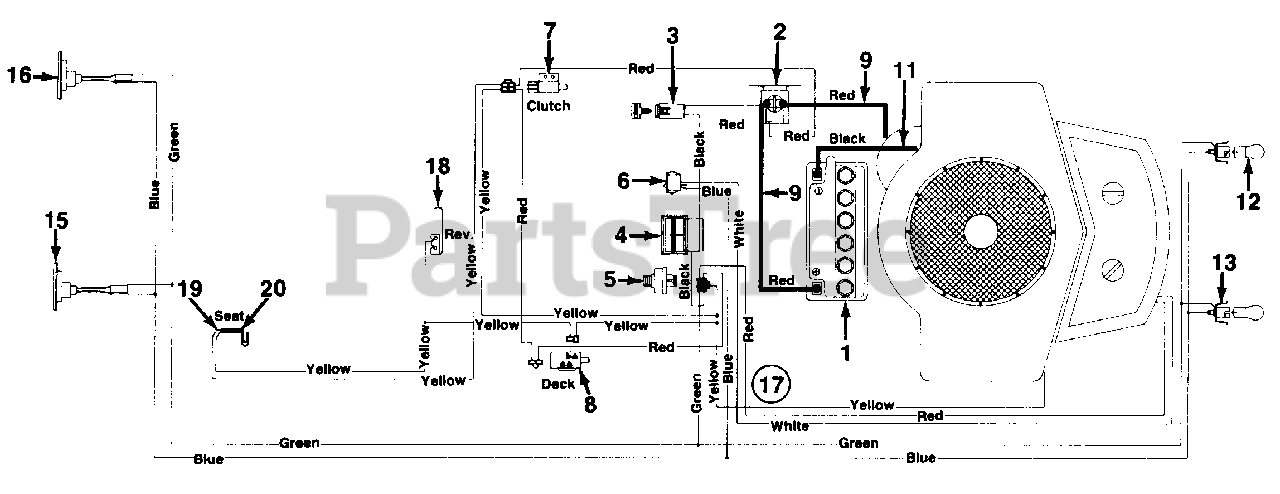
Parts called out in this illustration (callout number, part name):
1	Battery (275 Cold Crank Amps)
2	Solenoid
3	Fuse 7.5 AMP
4	Ammeter
5	Ignition Switch
6	Light Switch
7	Safety Switch
8	Safety Switch
9	Electric Wire 14" Lg.
11	Ground Wire 7.5" Lg.
12	Lamp
13	Socket
15	Taillight Ass'y.
16	Taillight Bulb
17	Wire Harness
18	Spring Switch
19	Safety Switch
20	Safety Switch
